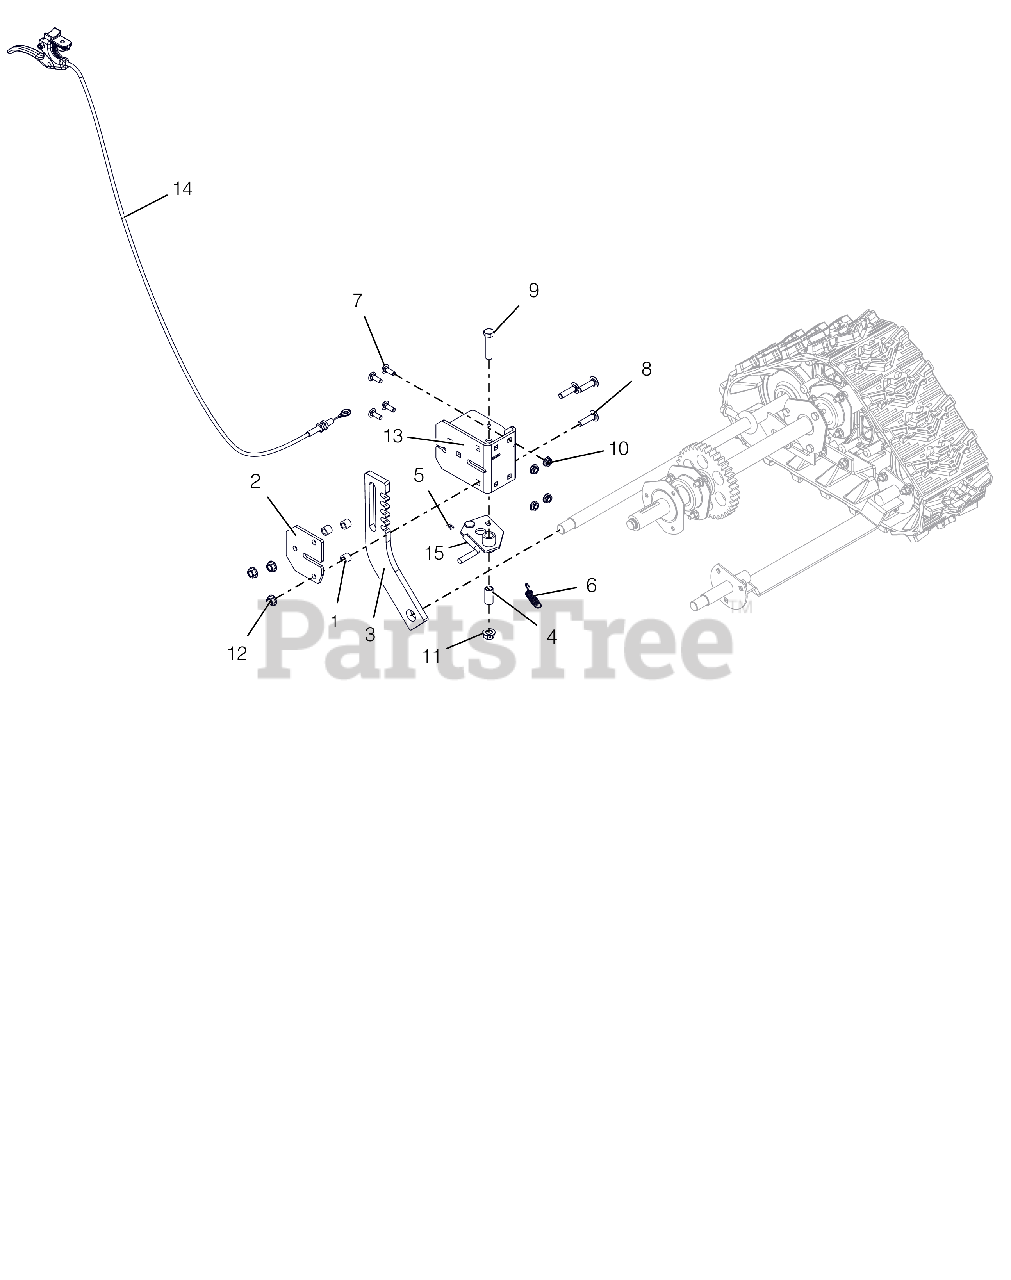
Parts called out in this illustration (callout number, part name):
1	SPACER .50 X .32 X .42
2	PLATE, HEIGHT ADJUSTER
3	STOP, HEIGHT ADJUSTER-CPT BLAC
4	BSHG-SLV .385X.500X1.045
5	PIN-HAIR INT .06X.18X.77
6	SPRING-EXT .047 X .438 X 1.85
7	@BLT-RDHDSQNK .25-20X.75 G5YZ
8	@BLT-RHDSHSQNK.31-18X1.25 G5YZ
9	@BLT-HEX .38-16X1.75 GR5 YWZC
10	@NUT-LK-CTR-FLG .25-20 YWZC
11	NUT-LK-CTR-FLG .38-16 YWZC
12	@NUT-LK-TOP-FLG .31-18 YWZC
13	BRACKET, HEIGHT ADJUSTER
14	CABLE, TRACK REMOTE
15	LOCK,HEIGHT ADJUSTER TRIGGER
